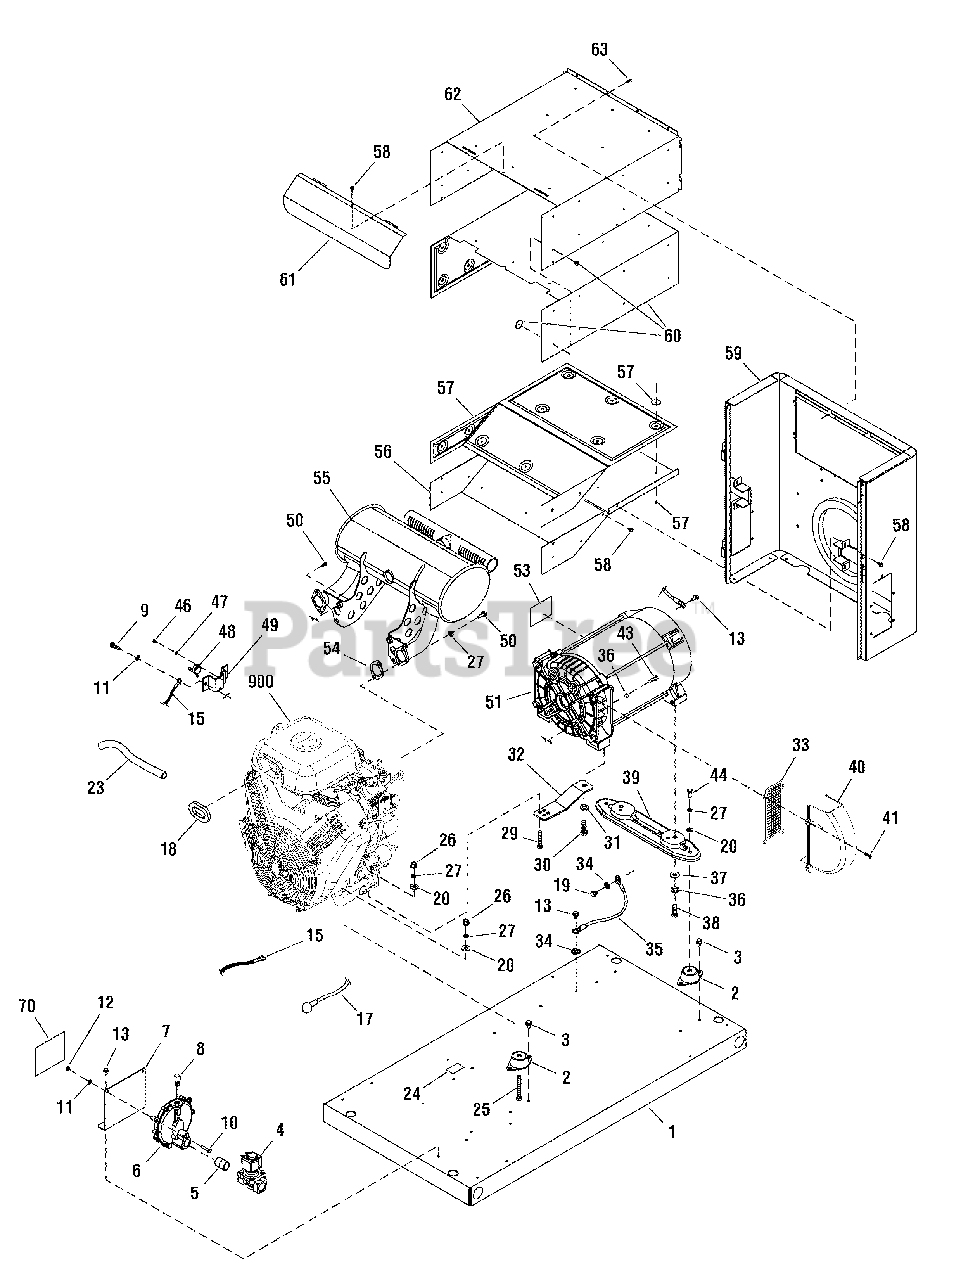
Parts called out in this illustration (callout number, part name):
1	BASE
2	MOUNT, Vibration
4	SOLENOID-GAS FUEL
6	REGULATOR-NG/LPG
7	BRACKET
9	* CAPSCREW, Hex Head, M6-1 x 16
10	* CAPSCREW, Hex Head, M6-1 x 30
11	* WASHER, Lock, 1/4
12	* NUT, M6-1
13	BOLT
15	CABLE-BTTRY, BLACK
17	CABLE-BTTRY, RED
18	TUBE
20	* WASHER, Flat, 5/16-M8
23	HOSE, Oil Drain
24	DECAL, Oil Drain
25	* CAPSCREW, Hex Head, 5/16-18 x 2-1/2
26	* NUT, 5/16-18
27	* WASHER, Lock, 5/16-M8
29	* CAPSCREW, Hex Head, 5/16-18 x 2
30	* CAPSCREW, Hex Head, M12 - 1-3/4 x 35
31	* WASHER, M12
32	SUPPORT, Engine
34	* WASHER, Shakeproof, Ext. M6-1/4
36	* WASHER, Lock, 3/8
37	* WASHER, Flat, 3/8-M10
38	* CAPSCREW, Hex Head, 3/8-16 x 1
39	SUPPORT, Alternator
43	* CAPSCREW, Socket Head, 3/8-16 x 1-1/4
44	* CAPSCREW, Socket Head, 5/16-18 x 3/4
46	* SCREW, Phillips Head, 4-40 x 3/16
47	* WASHER, Lock #4
49	PLATE, Temp Switch
50	SCREW
51	ALTERNATOR, Complete
53	DECAL
59	BULKHEAD, Alternator
62	BOX, Muffler Top
900	** ENGINE
